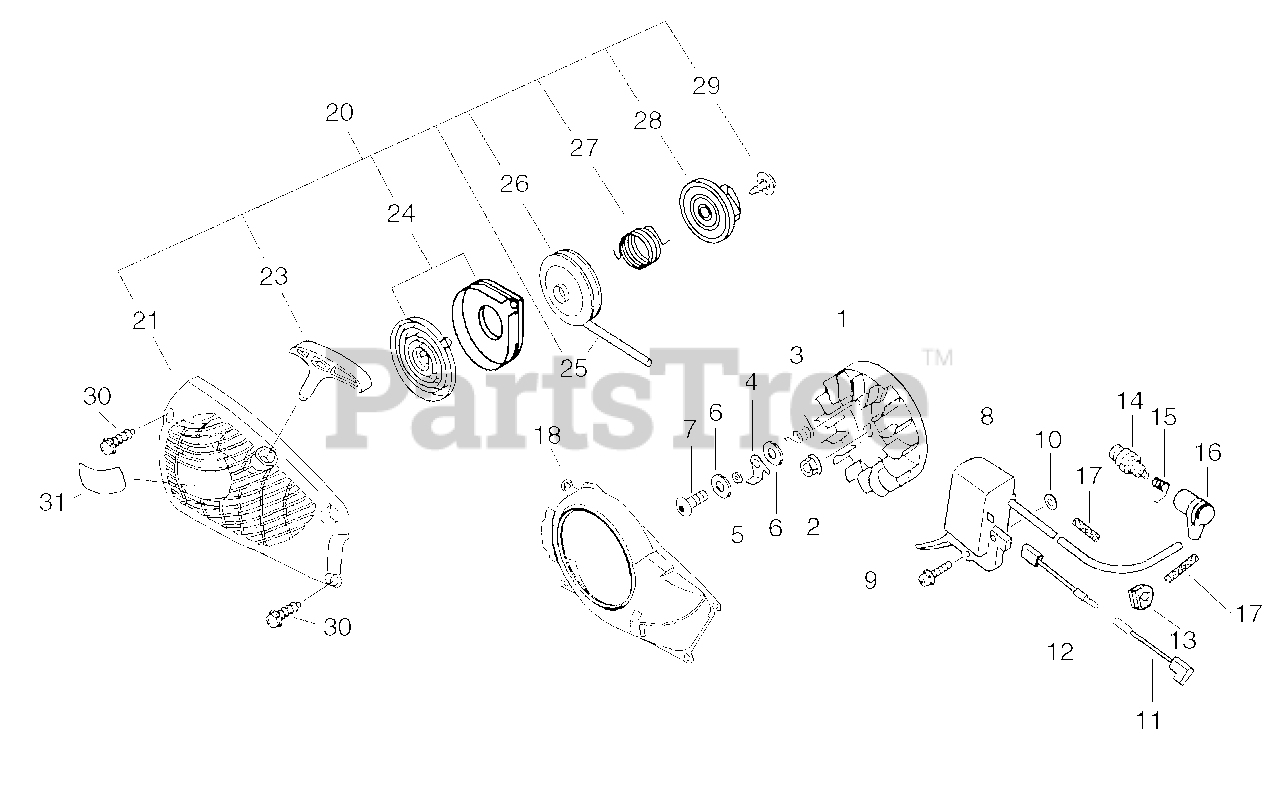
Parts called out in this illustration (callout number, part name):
1	FLYWHEEL
2	NUT, FLANGE M8
3	SPRING, TORSION
5	SPACER 5.2×8×2.1
6	WASHER 5.5×12×0.8
7	BOLT 5×14
8	COIL, IGNITION
9	SCREW 5×22
10	WASHER 5.2×12×3
12	LEAD - IGNITION
14	SPARK PLUG - BPM7A
15	TERMINAL, SPARK PLUG
16	CAP, SPARK PLUG
17	TUBE, INSULATOR 7×8.6×40
18	COVER, FAN
20	STARTER, RECOIL
21	STARTER, RECOIL
23	GRIP, STARTER
24	SPRING KIT, RECOIL
25	ROPE, STARTER 3.5×900
26	REEL, ROPE
27	SPRING, TORSION Ø21.1
28	PAWL CATCHER
29	SCREW
30	SCREW 4×16
31	LABEL, ECHO
